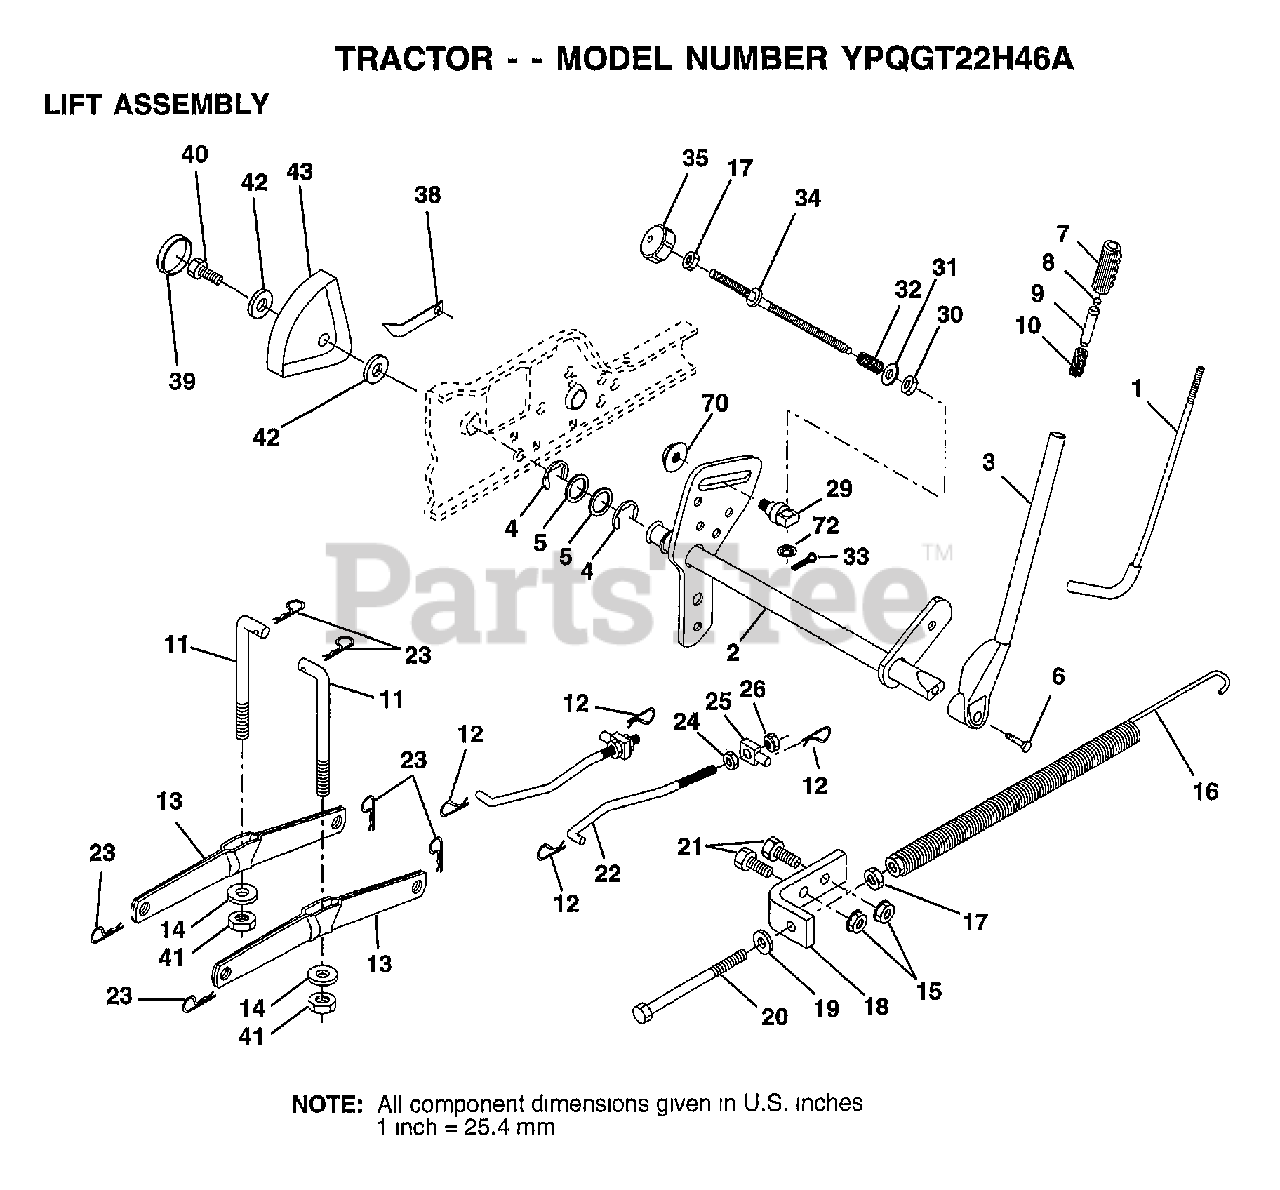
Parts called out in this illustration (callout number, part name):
1	LEVER ROD LT
2	SHAFT.ASM.LIFT.VGT
3	LEVER.ASM.LIFT.RH
4	E-RING
5	WASHER
6	"BOLT,HEX"
7	GRIP HANDLE
10	SPRING T
11	LINK.LIFT.MWR.VGT
12	RETAINER SPRING
13	ARM SUSP REAR
14	BEARING PVT LH
17	NUT
18	BRACKET SPRING AS
19	WASHER
20	BOLT-ADJ SPRING T
21	BOLT
22	LINK.FRONT
24	NUT
25	TRUNION
26	NUT LTV
29	TRUNNION
30	NUT T
31	WASHER
32	SPRING.COMP.INF.H
34	ROD.ADJ.LIFT
35	KNOB INF 3/8-16
38	POINTER-INDICAT
39	"PLUG,HOLE"
40	SCREW
41	NUT.CROWNLOCK.3/8
42	WASHER
43	HEIGHT INDICATOR
70	NUT.HXFLG.LOCK.
72	NUT PUSH M
